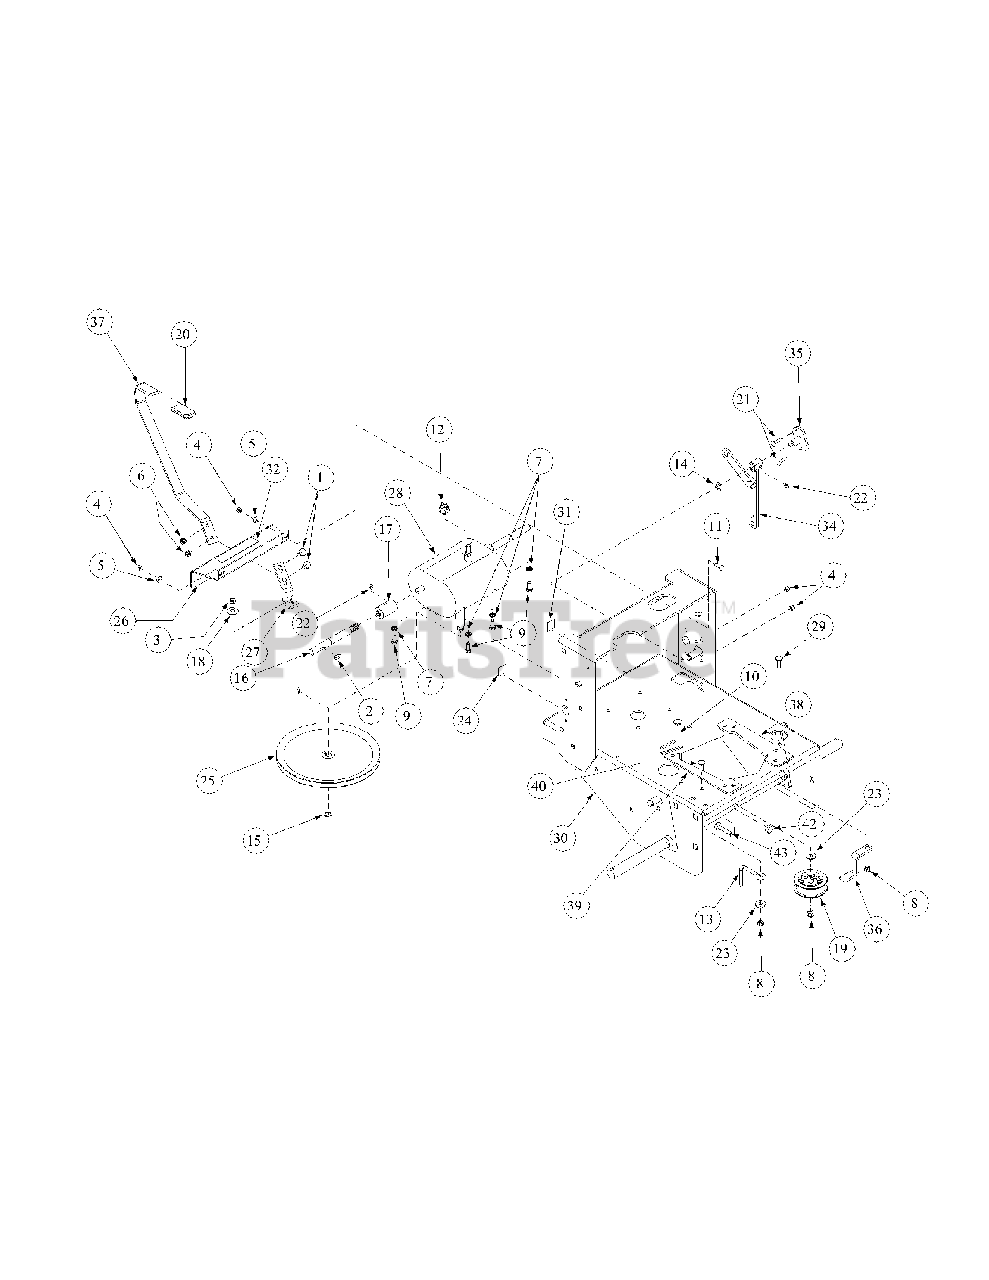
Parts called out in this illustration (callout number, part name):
1	Carriage Bolt, 5/16-18 x 1
2	Woodruff Key, 3/16 x 3/4
3	Jam Nut, Insert Lock, 3/8-24
4	Lock Nut, Nylon Insert, 1/4-20
5	Flat Washer, 1/4 Zinc
6	Nut, 5/16-18 Nylock
7	Lock Washer, 5/16 Zinc
8	Lock Nut, Nylon Insert, 3/8-16
9	Hex Cap Screw, 5/16-18 x 3/4
10	Carriage Bolt, 3/8-16 x2
11	Carriage Bolt, 1/4-20 x .750
12	Switch, WB Transmission
13	Drive Belt Guide
14	E-Ring, 5/8
15	External Retainer Ring
16	Jackshaft w/ Heavy Spline
17	Coupling w/Heavy Spline
18	Bell Washer, .39 ID x 1.13 OD x .062
19	Flat Idler Pulley w/Adapter
20	Grip, .250 x 1 x 3-1/2, Yellow
21	Carriage Bolt, 1/4-20 x 1.00
22	Grease Fitting, 1/4-28 x 3/16
23	Idler Washer
24	Decal "Made In America
25	Transmission Pulley
27	Shift Arm
28	Transmission, 5 Speed
29	Carriage Bolt, 3/8-16 x 1
30	Engine Deck Assembly
31	Label, Warning, Open Belt Drive
32	Label, Mower Instruction
34	Clutch, Bellecrank Weldment
35	Bellecrank Pivot, Weldment
36	Engine Belt Guide
38	Engine Spacer, LH
39	Engine Spacer, RH
40	Carriage Screw, 3/8-16 x 1.25
42	Hex Lock Nut, 1/4-20
43	Hex Cap Screw, 1/4-20 x 2
